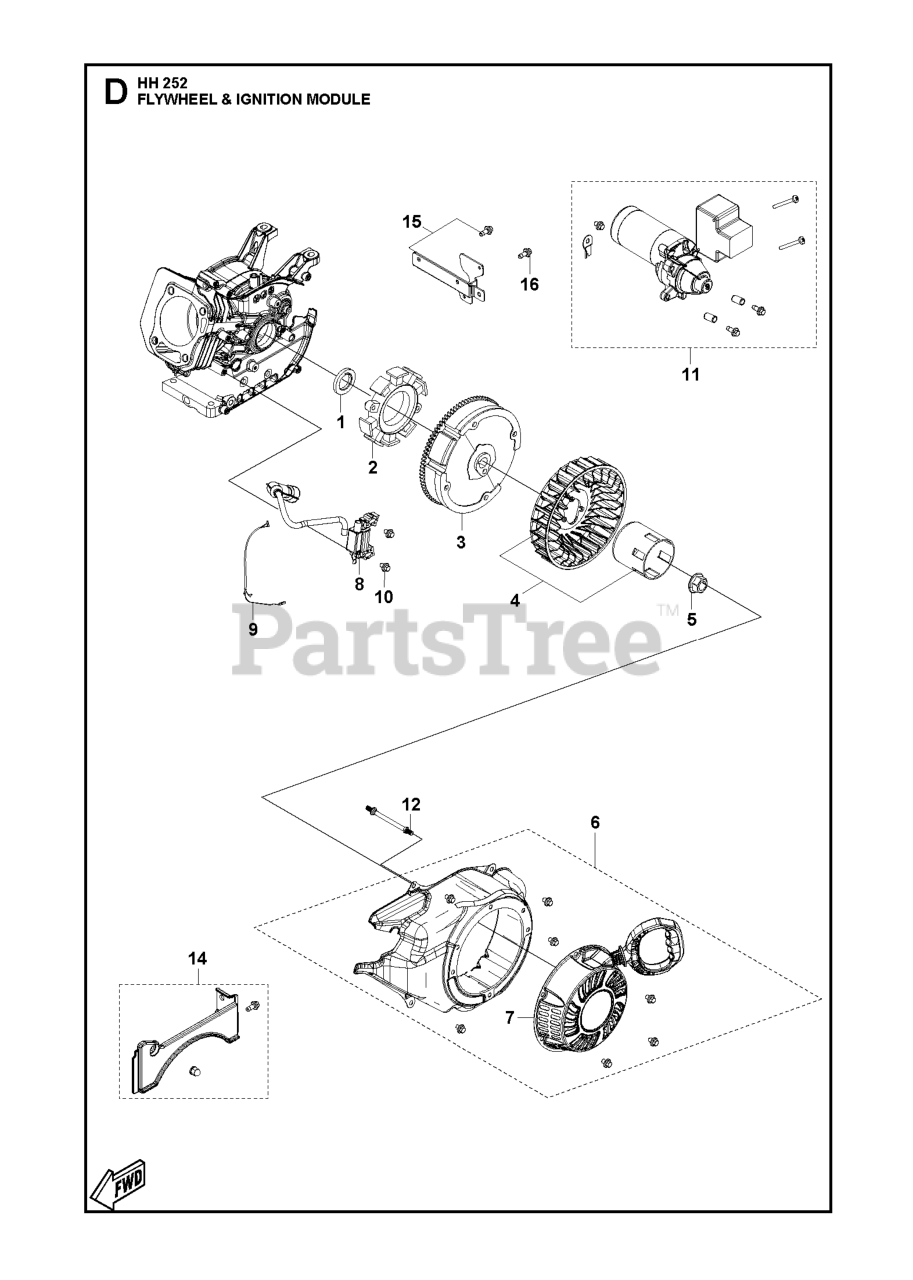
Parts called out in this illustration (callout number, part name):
1	SEAL OIL SEAL
2	COIL CHARGE COIL
3	FLYWHEEL
6	STARTER ASSY
7	STARTER HANDLE ASSY
8	IGNITION COIL
9	WIRE IGNITION COIL STOP ENGINE
10	BOLT
11	STARTER MOTOR
14	GUARD FRONT GUARD
15	SUPPORT KIT
16	BOLT
